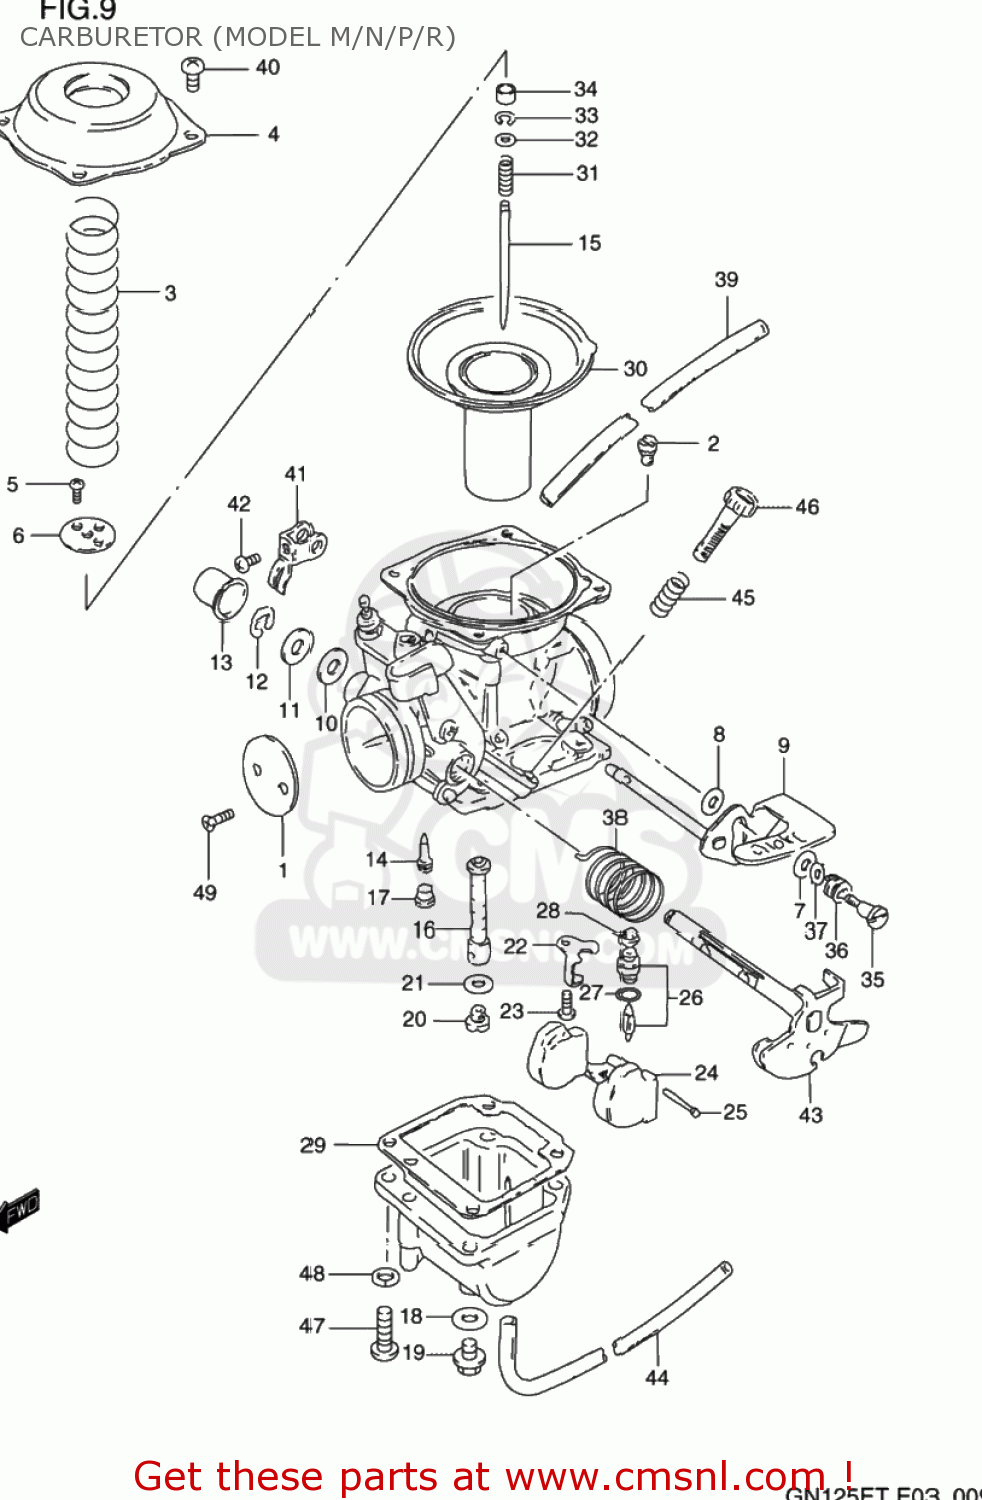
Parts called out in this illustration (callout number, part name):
1	VALVE,THROTTLE
2	JET,MAIN(180)
3	SPRING
4	COVER
5	SCREW
6	PLATE
7	PACKING (NAS)
8	WASHER,STARTER LEVER (4.1X12X0.8)
9	SHAFT ASSY,STARTER
10	SEAL
11	GASKET,THROTTLE SHAFT (NAS)
12	E RING
13	CAP
14	JET,PILOT(35)
15	NEEDLE,JET
16	JET,NEEDLE(P-2)
17	PLUG,NEEDLE JET
18	GASKET (NAS)
19	PLUG,DRAIN
20	JET,MAIN(97.5)
21	WASHER,NEEDLE NOZZLE
22	PLATE
23	SCREW
24	FLOAT
25	PIN,FLOAT
26	VALVE ASSY,NEEDLE
27	O-RING,NEEDLE VALVE
28	FILTER
29	GASKET,FLOAT CHAMBER (NAS)
30	DIAPHRAGM ASSEMBLY
31	SPRING
32	WASHER
33	CLIP
34	RING
35	SCREW
36	SPRING
37	WASHER,STARTER SHAFT
38	SPRING,THROTTLE SHAFT
39	HOSE
40	SCREW
41	LEVER
42	SCREW
43	SHAFT,THROTTLE
44	HOSE
45	SPRING,THROTTLE SCREW
46	SCREW,THROTTLE STOP
47	SCREW
48	LOCK WASHER
49	SCREW
